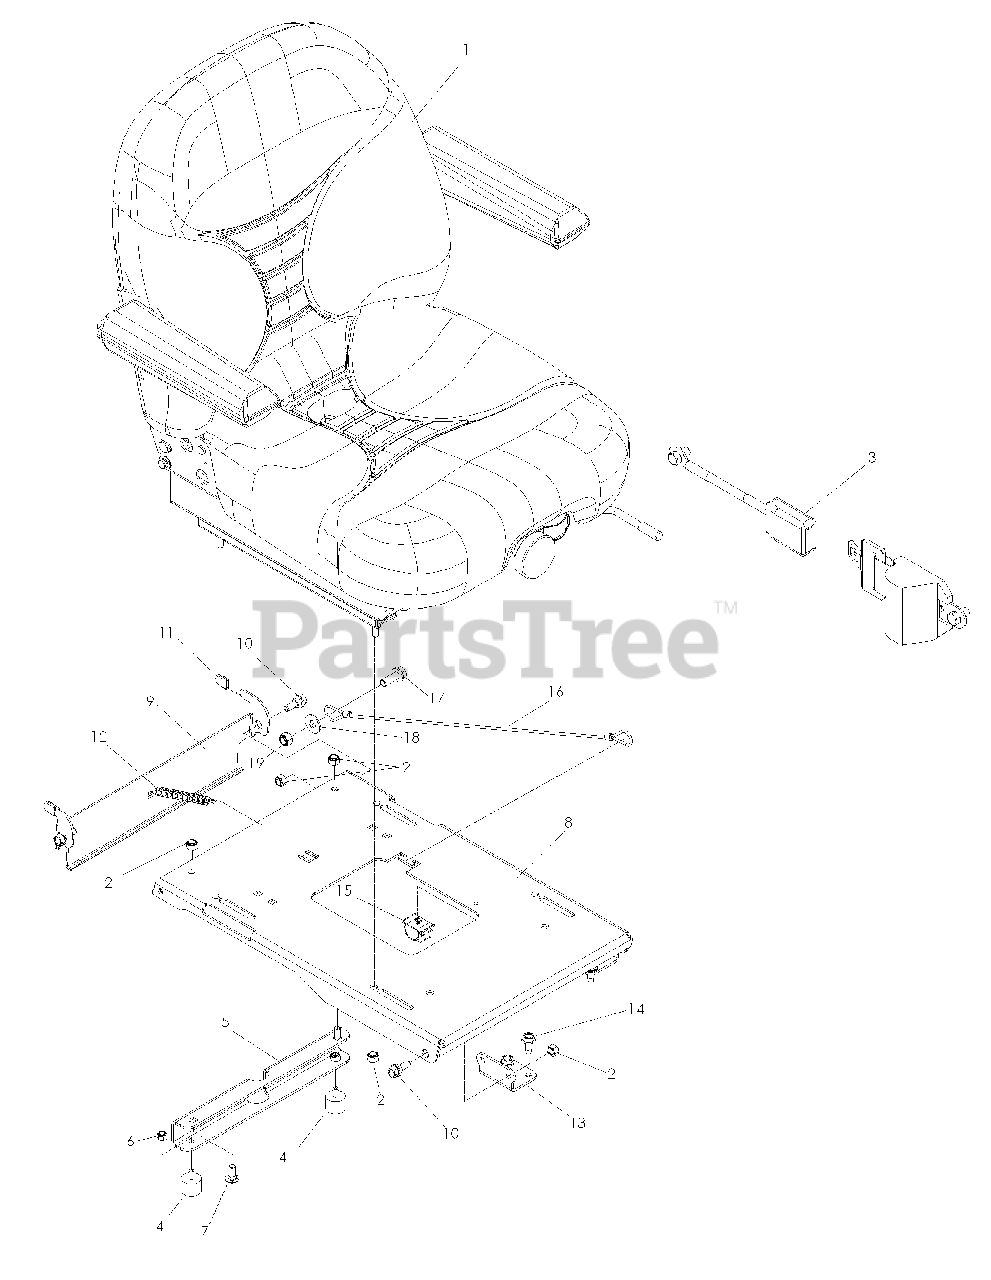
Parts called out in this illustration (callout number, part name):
2	NUT 5/16-18 HEX NYLOC
3	SEAT BELT-RETRACTABLE
4	STUD PLATE MOUNT
5	STANDOFF, SEAT PAN
6	NUT 1/4-20 HEX NYLOC
7	RHSNB 5/16-18 x 3/4
9	LATCH, SEAT
10	SB 5/16-18 HEX HD
11	GRIP, VINYL
13	PIVOT SEAT PAN
14	BOLT 5/16-18 x 3/4 THD FRM
15	WIRE CLIP PUSH-MOUNT
16	SEAT LANYARD
17	HCS 3/8-16 x 1 WHIZLK
18	WASHER 3/8 FLAT STD
19	NUT 3/8-16 HEX NYLOC
